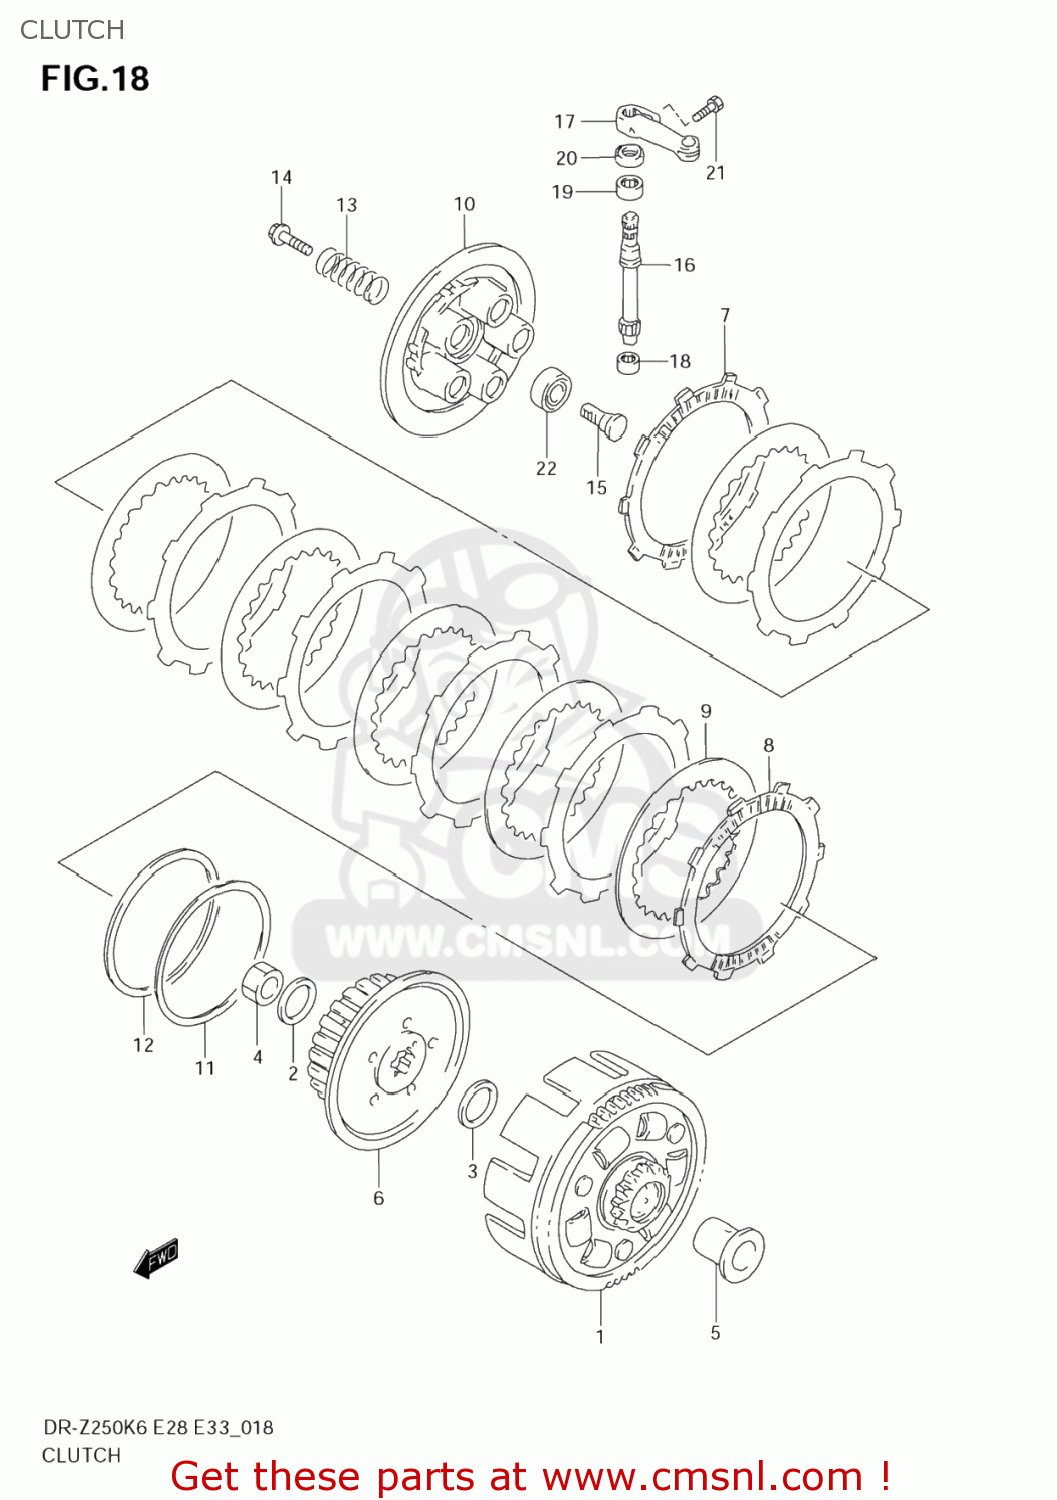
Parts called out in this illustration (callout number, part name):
1	GEAR ASSY,PRIMARY(NT:67/15)
2	WASHER
3	WASHER
4	NUT
5	SPACER,PRIMARY DRIVEN GEAR
6	HUB,CLUTCH SLEEVE
7	PLATE,CLUTCH DRIVE (NAS)
8	PLATE,CLUTCH DRIVE
9	PLATE,CLUTCH DRIVEN
10	DISC,CLUTCH PRESSURE
11	SEAT,WAVE WASHER
12	WASHER,CLUTCH PLATE
13	SPRING,CLUTCH
14	BOLT,CLUTCH SPRING
15	RACK,CLUTCH RELEASE
16	PINION,CLUTCH RELEASE
17	ARM,CLUTCH RELEASE
18	BEARING(9X13X10)
19	BEARING(12X16X10)
20	SEAL,OIL(10X17X5)
21	BOLT
22	BEARING(12X28X8)
